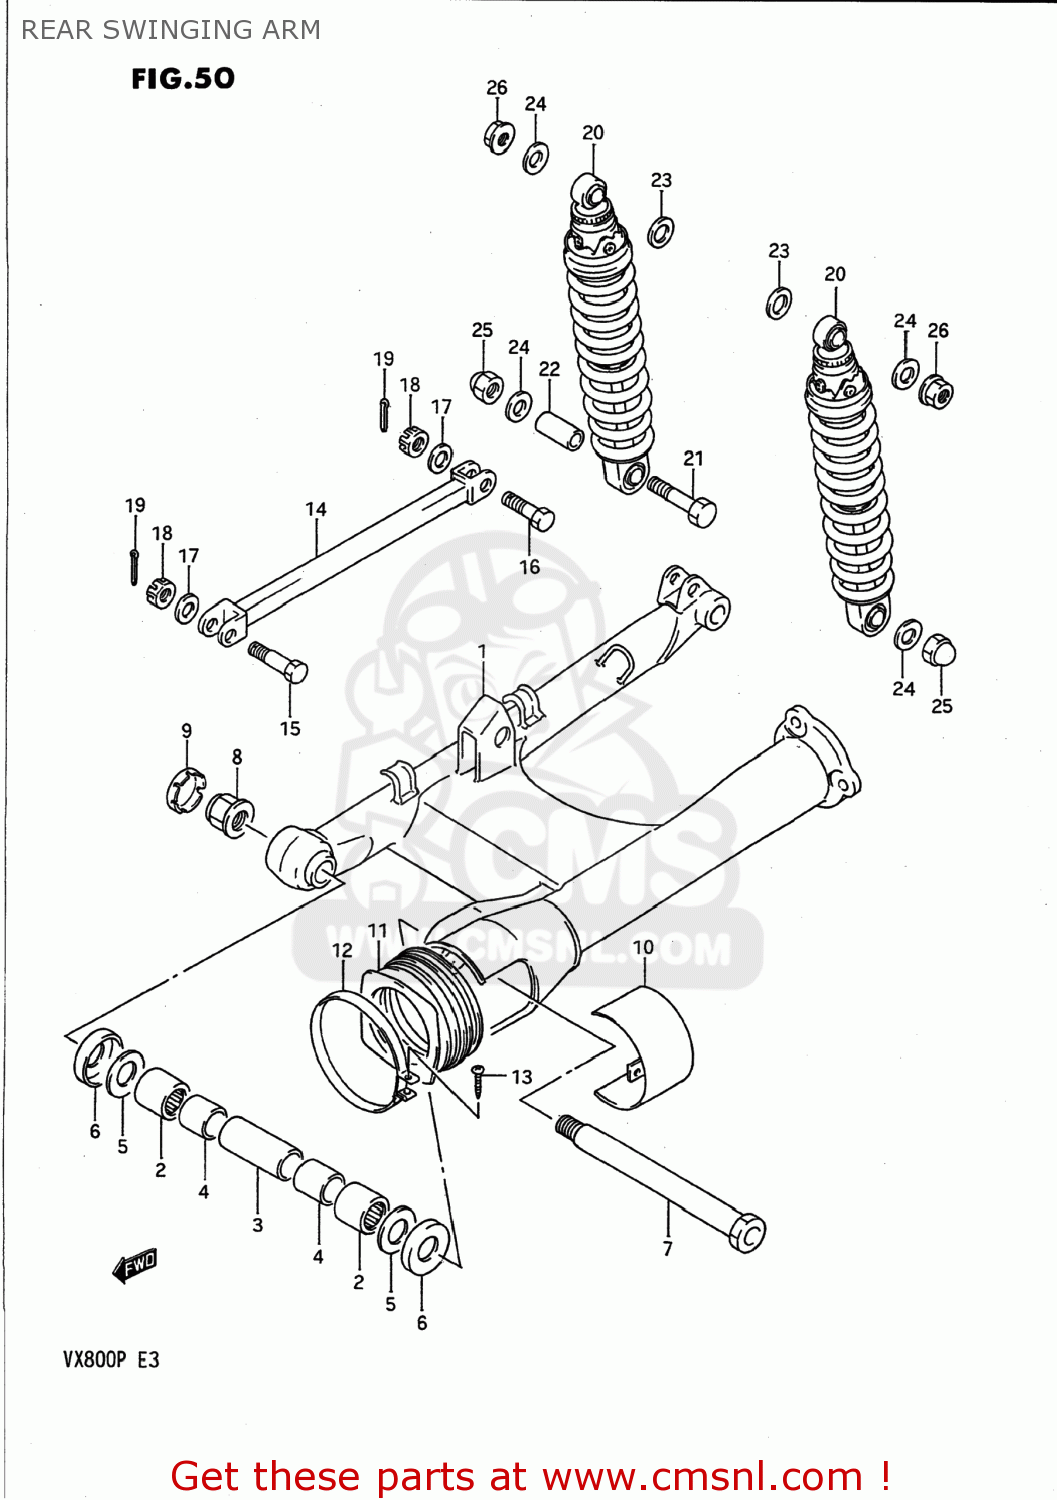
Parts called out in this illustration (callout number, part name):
1	SWING ARM,REAR
2	BEARING(25X33X30)
3	SPACER,REAR SWING ARM PIVOT
4	SPACER,RR SWGARM PIVOT BERRING
5	WASHER
6	COVER,RR SWGARM PIVOT SEAL
7	SHAFT,RR SWINGINGARM PIVOT
8	NUT ,18MM
9	CAP,RR SWINGING ARM PIVOT
10	COVER,SWGARM PIVOT,L
11	BOOT,PROPELLER SHAFT
12	CLAMP
13	SCREW 4X25
14	TORQUE LINK,REAR
15	BOLT(10X41)
16	BOLT(10X35)
17	WASHER (10X18X3.2)
18	NUT
19	PIN 20X20
20	ABSORBER ASSEMBLY,REAR SHOCK
21	BOLT(10X39)
22	SPACER (10.2X14X20.7)
23	WASHER
24	WASHER
25	NUT
26	NUT
